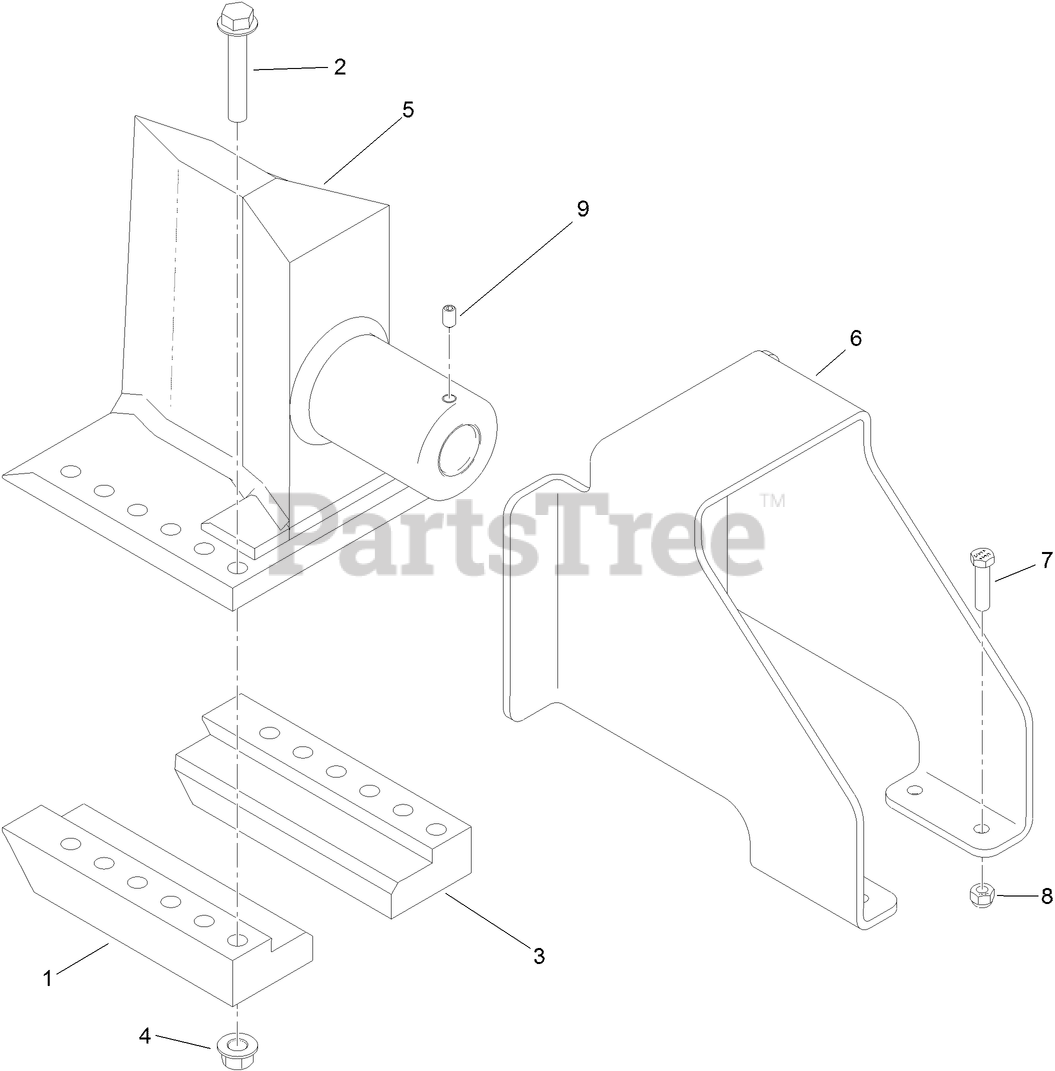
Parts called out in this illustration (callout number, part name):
1	BAR-SLIDE, LH
2	SCREW-HF
3	BAR-SLIDE, RH
4	NUT-LOCK
5	SPLITTER WEDGE ASM
6	PLATE-DISLODGER
7	SCREW-HH
8	NUT-LOCK, NI
9	SCREW-SET
